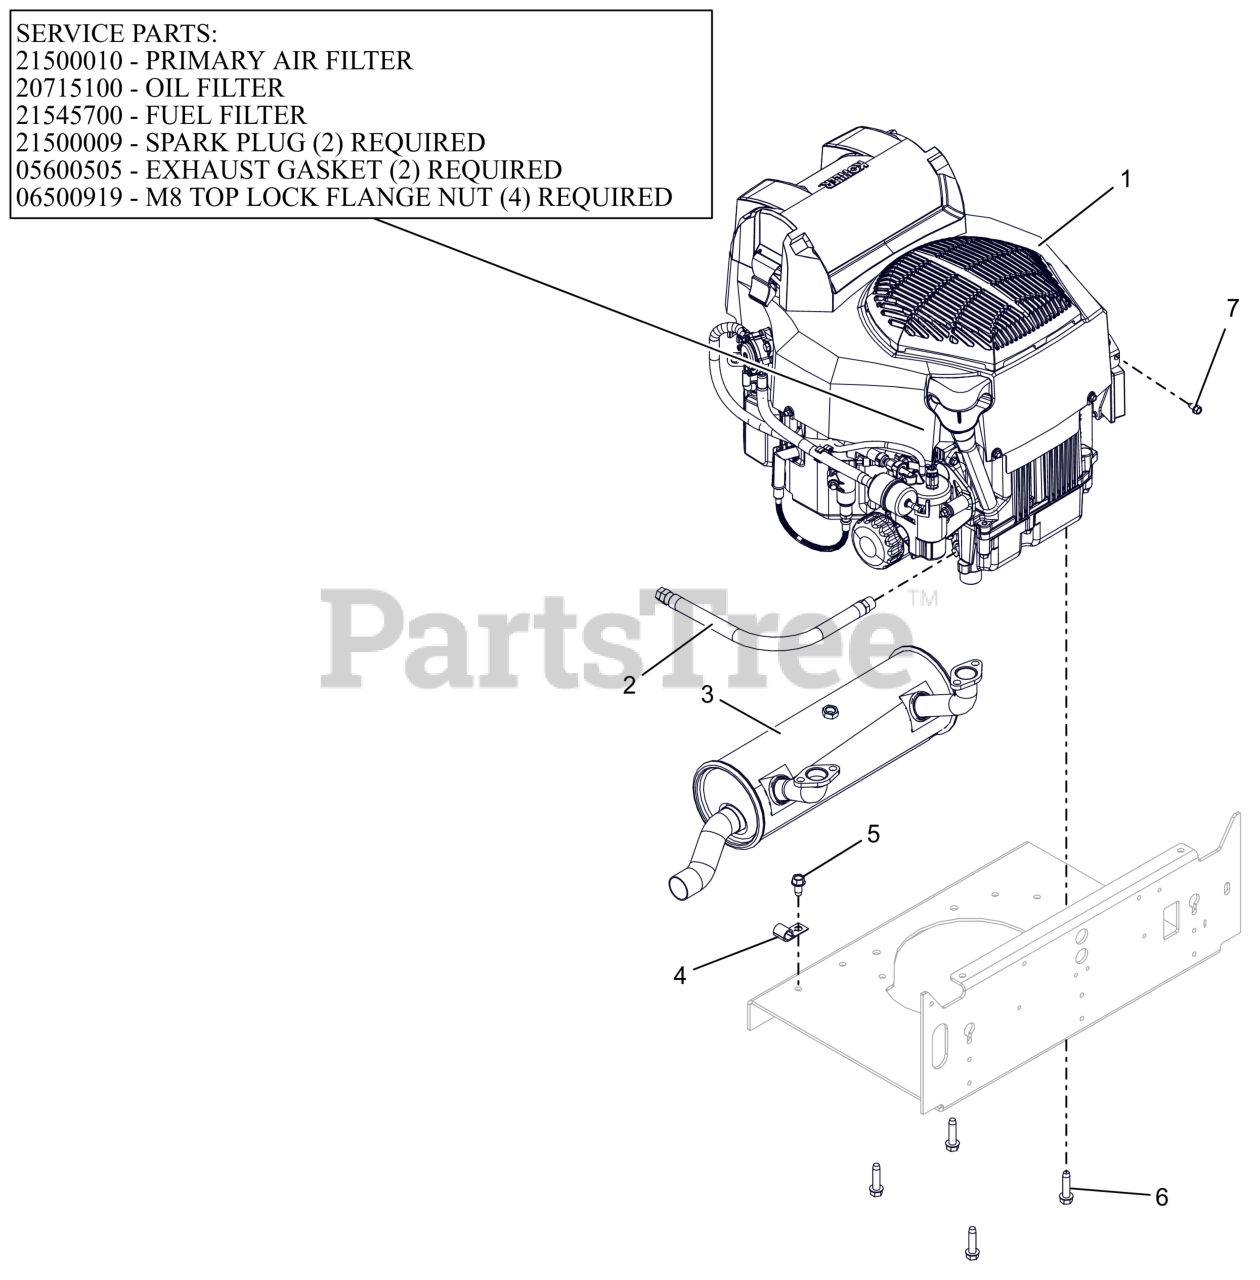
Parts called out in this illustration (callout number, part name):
1	ENGINE, KOHLER EZT740 EFI
1	AIR CLEANER, KOHLER CONFIDANT
1	OIL FILTER KOHLER
1	FILTER-FUEL KOHLER COURAGE PRO
1	PLUG, SPARK KOHLER
1	GASKET, MUFFLER KOHLER TWIN
1	NUT-LK-TOP-FLG M8 ZCC
2	HOSE, OIL DRAIN
3	MUFFLER, ZT725/740 EFI
5	SCR,TAP .375-16X.75 HWH TR ZCC
6	SCR-TAP .38-16X1.50 HWH ZCC
7	SCR-TAP .25-20X.50 HWH ZCC
